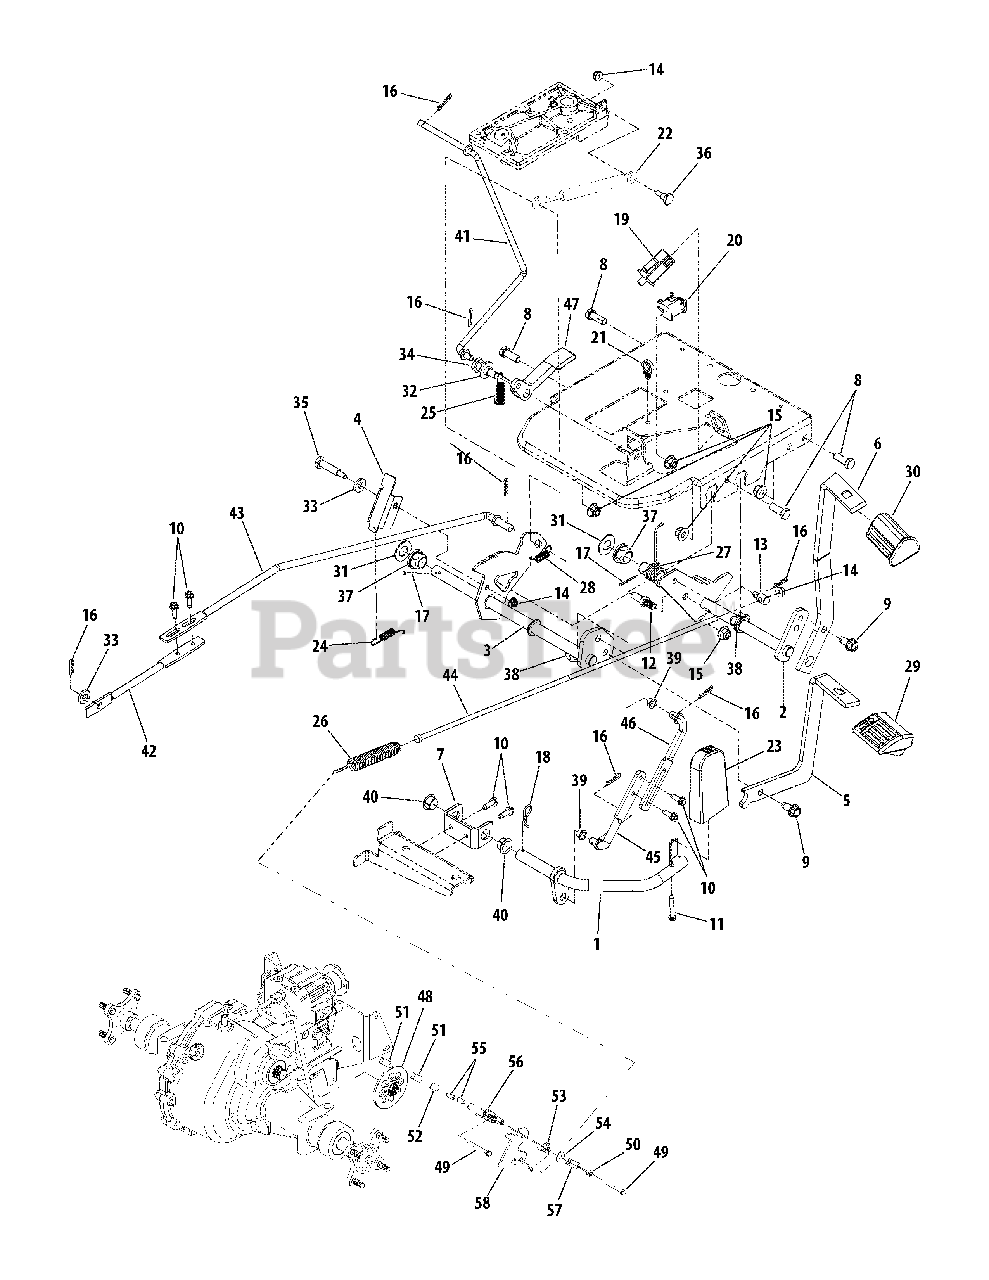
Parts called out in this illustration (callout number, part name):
3	Shaft Assy, Forward/Reverse
4	Bracket, Reverse Switch
5	Pedal, Forward
6	Pedal, Brake
8	Screw, Hex Cap, 3/8-16 x 1.0 GR5
9	Screw, Hex Wash Hd Tapp, 3/8-16x .75
10	Screw, Hex Wash Hd Tapp, 1/4-20x .75
11	Screw, Truss Mach, #12 x 1.5
12	Pin, 3/8-16 x 1.0
13	Ferrule, Adjustment, 1/4-20 Thrd
14	Nut, Hex Flange Lock, 1/4-20
15	Nut, Hex Flange Lock, 3/8-16
16	Pin, Internal Cotter, 5/16 Dia x 1.12
17	Pin, Cotter, 3/32 x 1.0
18	Pin, Internal Cotter, 3/8 Dia x 1.62
19	Switch, Interlock (Brake)
20	Switch, Snap Mount (Reverse)
21	Clip, Cable Retainer
22	Cylinder, Damper, .59 OD x 7.84 Lg
23	Pedal, Reverse
24	Spring, Extension, .38 OD x 2.1
25	Sping, Extension
26	Spring, Extension
27	Spring, Torsion
28	Spring, Extension, .375 OD x 1.44
29	Pad, Forward Foot Control
30	Pad, Brake Foot
31	Washer, Flat, .64 x 1.24 x .06 HT
32	Washer, Flat, .51 x 1.0 x .125
33	Washer, Flat, .407 x .812 x .135 HT
34	Shoulder Bolt, .50 OD x .840
35	Screw, Shoulder, .374 x 1.375
36	Screw, Shoulder, .375 x .380:1/4-20
37	Bearing, Hex Flange
38	Bearing, Hex Flange Split
39	Bearing, Flange, .375 x .58 x .25
40	Bearing, Flange, .625 x .938 x .344
41	Rod, Cruise
42	Rod, Rear F/R Control
43	Rod, Front F/R Control
44	Rod, Brake
45	Rod, Rear Connecting
46	Rod, Front Connecting
47	Latch, Cruise
48	Disc, Brake
49	Screw, Hex Wash Hd, Tapp, 1/4-20 x 2.375
50	Nut, Hex Nylon Lock, 5/16-24
51	Pad, Brake
52	Plate, Puck
53	Spring, Torsion
54	Washer, Flat, .343 x .88 x .062
55	Pin, Brake Actuating
56	Yoke, Brake
57	Bracket, Brake Anti Rotation
58	Arm, Brake Actuator
